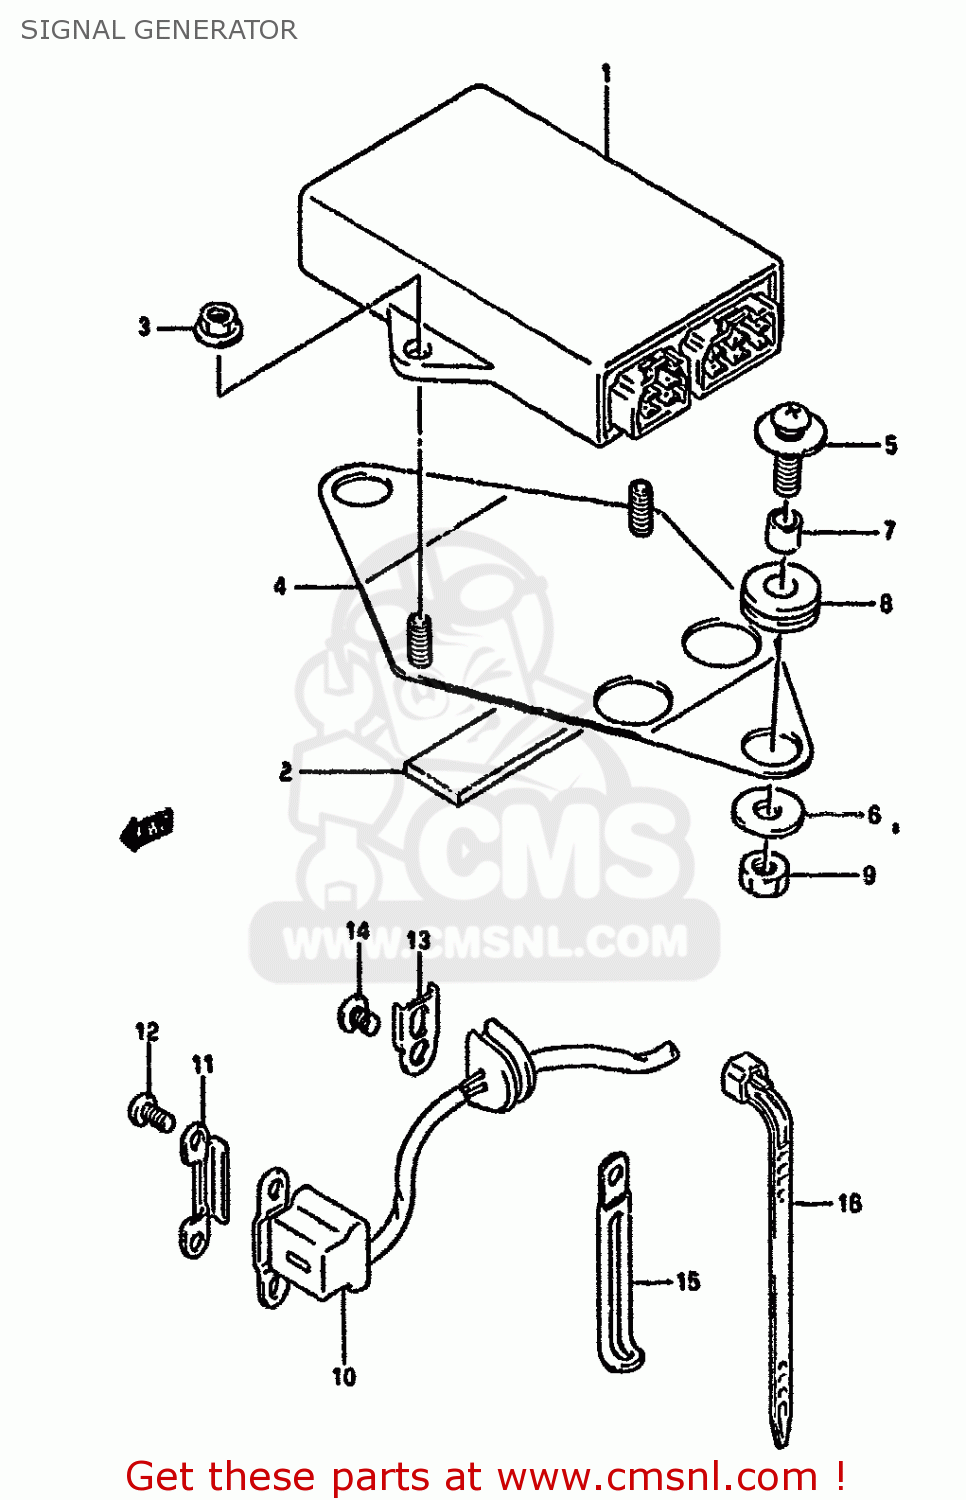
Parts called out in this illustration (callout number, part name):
1	IGNITOR
2	PROTECTOR,20X9
3	NUT
4	PLATE,IGNITOR
5	SCREW(6X20)
6	WASHER
7	SPACER (6.4X9X10.5)
8	CUSHION
9	NUT
10	GENERATOR ASSY,SIGNAL
11	PROTECTOR,SIGNAL GEN LEAD WIRE
12	SCREW
13	CLAMP,GENERATOR LEAD WIRE
14	SCREW
15	CLAMP
16	CLAMP(L:125)
